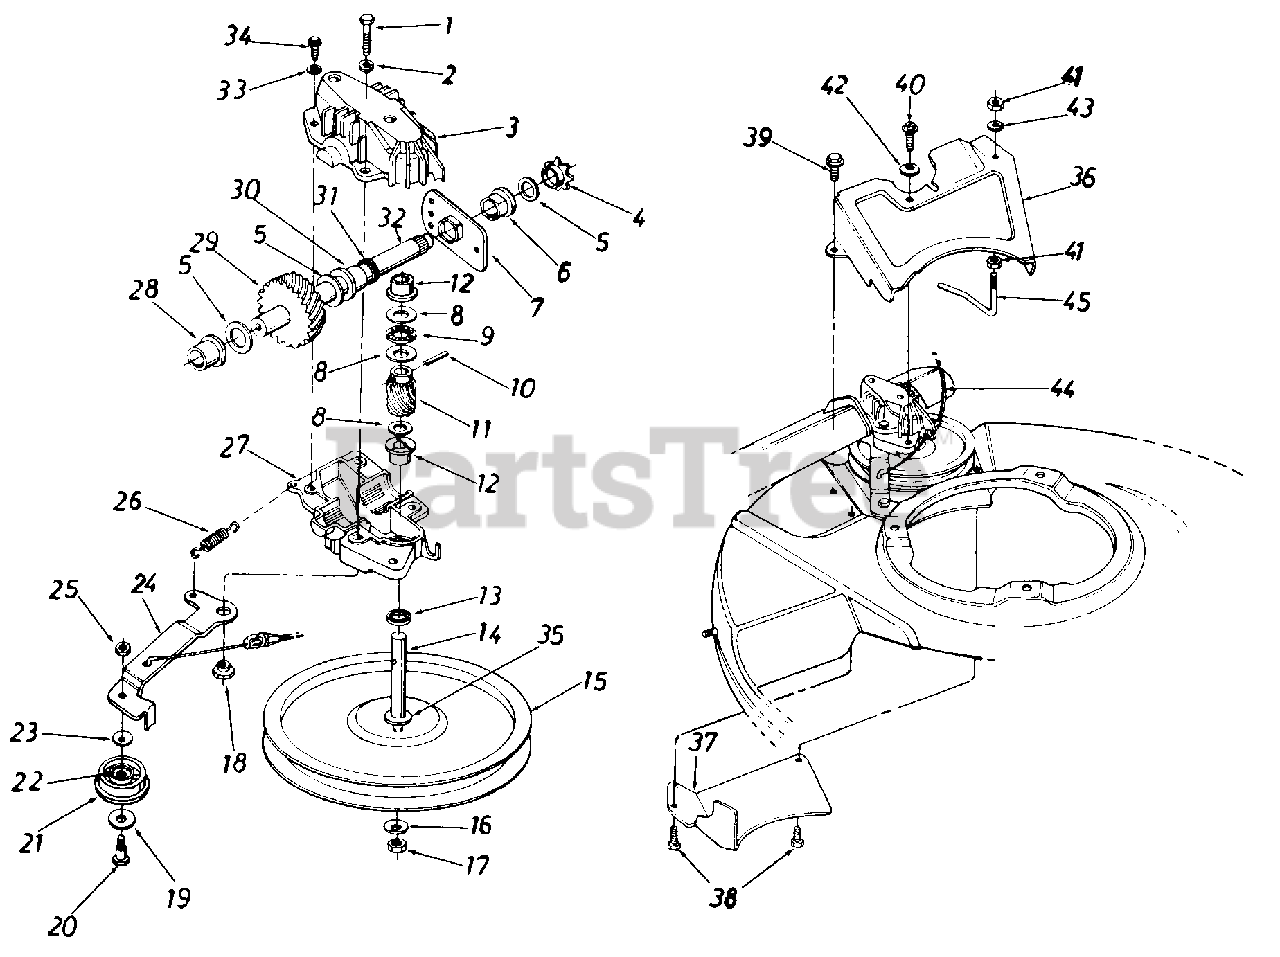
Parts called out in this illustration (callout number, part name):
1	Hex Bolt 1/4-20 x 1.25" Lg.
2	L-Wash. 1/4" I.D.
3	Upper Hsg. Half
4	#48 Sprocket 7 Tooth x 1/2 Pitch
5	Fl-Wash. 5/8" I.D. x .030
6	Hex Flange Brg. .631" I.D.
7	Hex Bearing Cup
8	Thrust Wash. .382" I.D. x .70" O.D.
9	Thrust Bearing .375" I.D. x .812" O.D.
10	Spring Pin Spir. 1/8" x .62" Heavy
11	11 Tooth Helical Gear
12	Flange Bearing
13	Oil Seal
14	Pulley-Transmission Shaft
15	Fl-Pulley 5.06" O.D.
16	Bell-Wash. .265" I.D. x .75"
17	Hex L-Nut 1/4-28 Thd.
18	Shld. Spacer .375" Dia. x .170
19	Fl-Wash. .390" I.D. x 1.0"
20	Shld. Bolt .375" Dia. x .40"
21	Fl-Idler Plastic 1.50" Dia.
22	Needle Brg. .375" x .31
23	Bell-Wash. .265" I.D. x .75"
24	Idler Brk't. Ass'y.
25	Hex Patch L-Nut 1/4-28 Thd.
26	Extension Spring 1.12" Lg.
27	Lower Hsg. Half
28	Flange Bearing .566 Dia.
29	33 Tooth Helical Gear
30	Flange Bearing .629 Dia.
31	Oil Seal .625 Dia.
32	Gear Sprocket Shaft
33	L-Wash. #10 I.D.
34	Hex B-Tap Scr. #10 x .62"
35	Hex Washer .26" x .88"
36	Transmission Belt Guard
37	Belt Cover
38	Hex B-Tap Scr. 1/4 x .38" Lg.
39	Hex AB-Tap Scr. 1/4 x .50" Lg.
40	Hex B-Tap Scr. 1/4 x .62" Lg.
41	Hex Nut 1/4-20 Thd.
42	Bell-Wash. .265" I.D. x 75"
43	L-Wash. 1/4" I.D.
44	S.P. Cable-48" Lg.
45	S.P. Belt Guard
